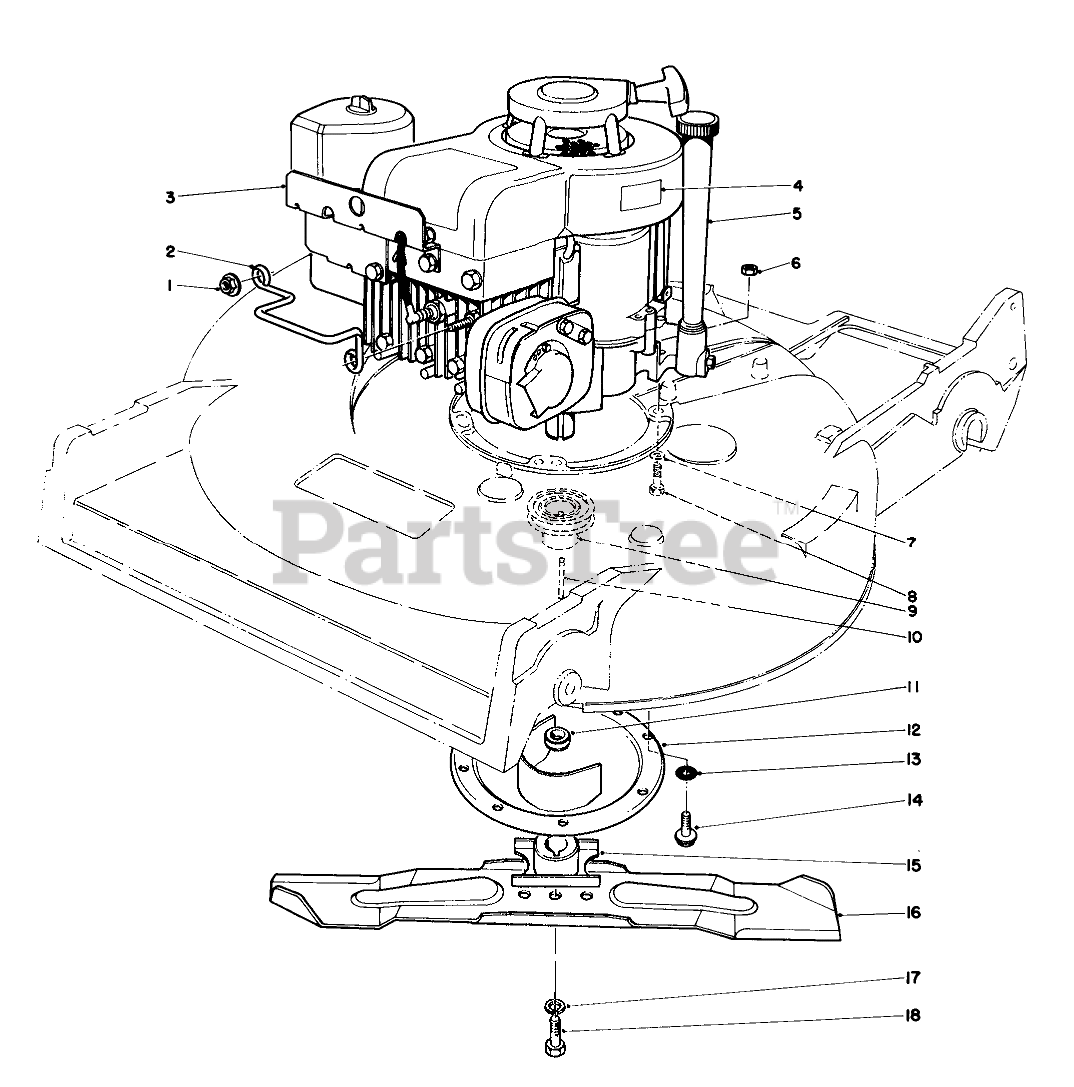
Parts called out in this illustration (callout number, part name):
1	NUT-HF
2	Protector-Spark Plug
3	ENGINE GD BRKT
4	Decal-Oil Caution
5	Engine
6	NUT-LOCK, CONE
7	WASHER-PLAIN
8	SCREW-HH
9	PULLEY DRIVER
10	KEY-SQUARE
11	BLADE RETAINER SPACER
12	Crankshaft Protector Assy.
13	WASHER-LOCK, INTERNAL
14	SCREW-HWHTF
15	BLADE RETAINER W A
16	BLADE-21in
17	WASHER-LOCK
18	BLADE SCREW
